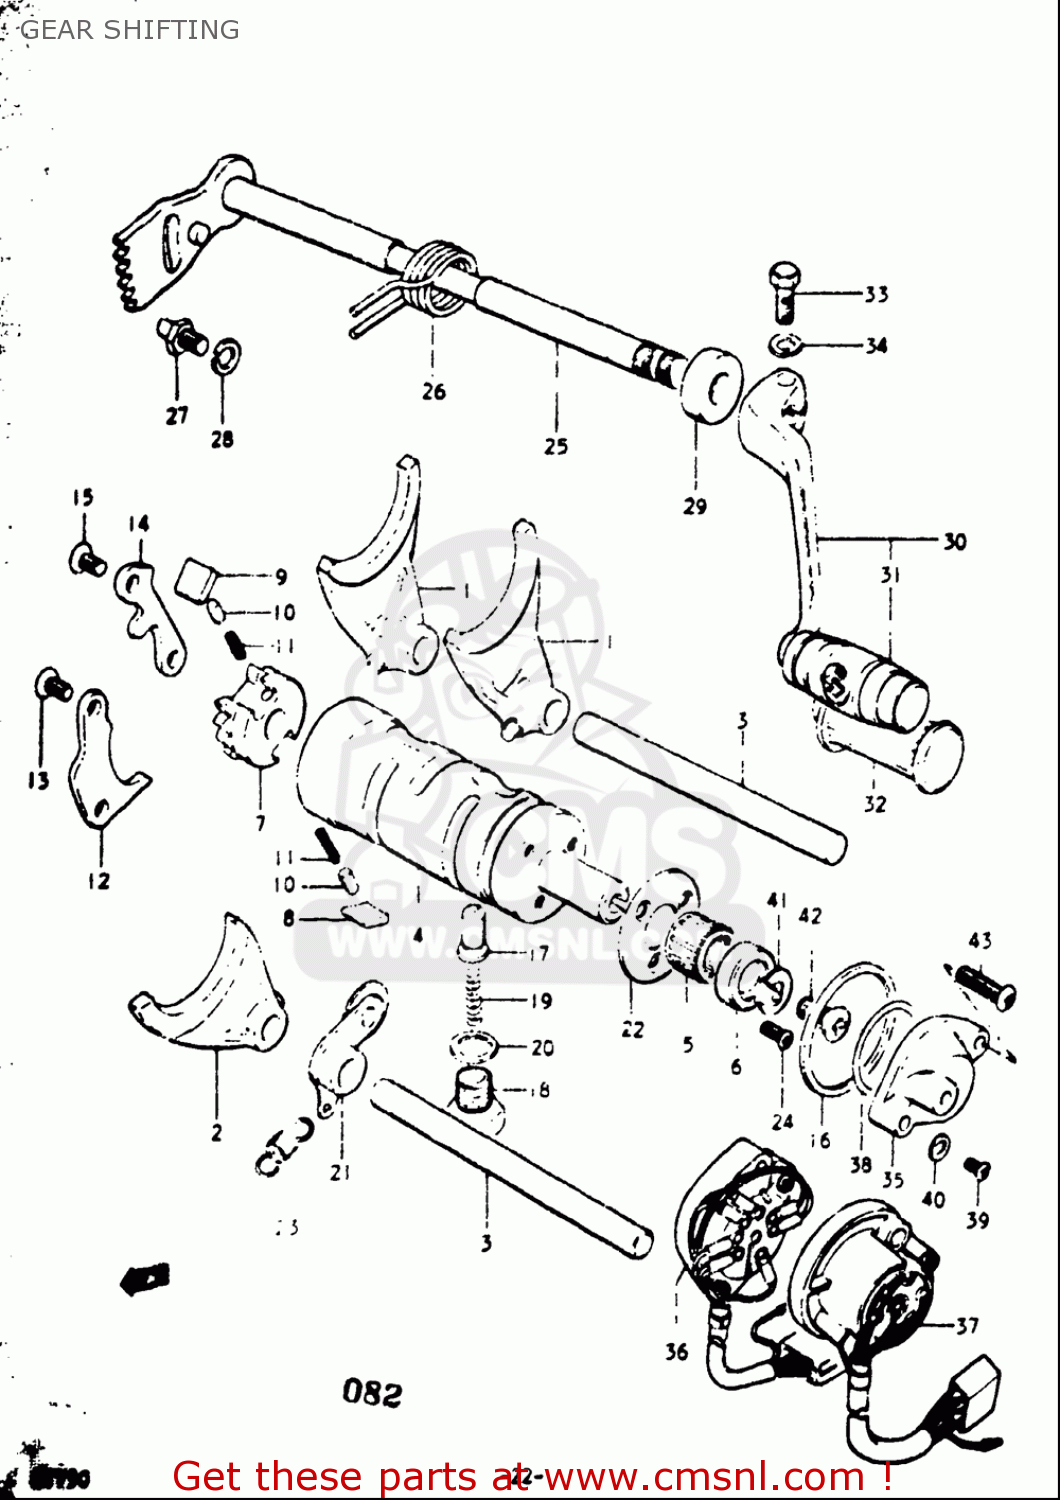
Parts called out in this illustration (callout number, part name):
3	SHAFT,GEAR SHIFT FORK
5	BEARING(16X22X12)
6	SEAL,OIL(16X24X7)
7	GEAR,GEAR SHIFT CAM DRIVEN
8	PAWL,GEAR SHIFT NO.1
9	PAWL,GEAR SHIFT NO.2
10	PIN(5X8)
11	SPRING
12	LIFTER,GEAR SHIFT PAWL
13	SCREW
14	GUIDE,GEAR SHIFT
15	SCREW
16	WASHER(40X45X1)
17	STOPPER,GEAR SHIFT CAM NO.2
18	HOLDER,GEAR SHIFT CAM STOP SPR
19	SPRING
20	GASKET(14X19.2X2) (NAS)
23	SPRING
24	SCREW
26	SPRING
27	STOPPER,GEAR SHIFT ARM
28	WASHER,LOCK
29	SEAL,OIL (12X22X9)
30	LEVER ASSY,GEAR SHIFT
31	RUBBER,GEAR SHIFT PEDAL
32	RUBBER,GEAR SHIFT PEDAL
33	BOLT
34	WASHER,LOCK
35	BODY,GEAR SHIFT SWITCH
37	SWITCH
38	O RING(D:1.9,ID:27.7)
39	SCREW
40	WASHER
41	CONTACT,GEAR SHIFT SWITCH
42	SCREW
43	SCREW
